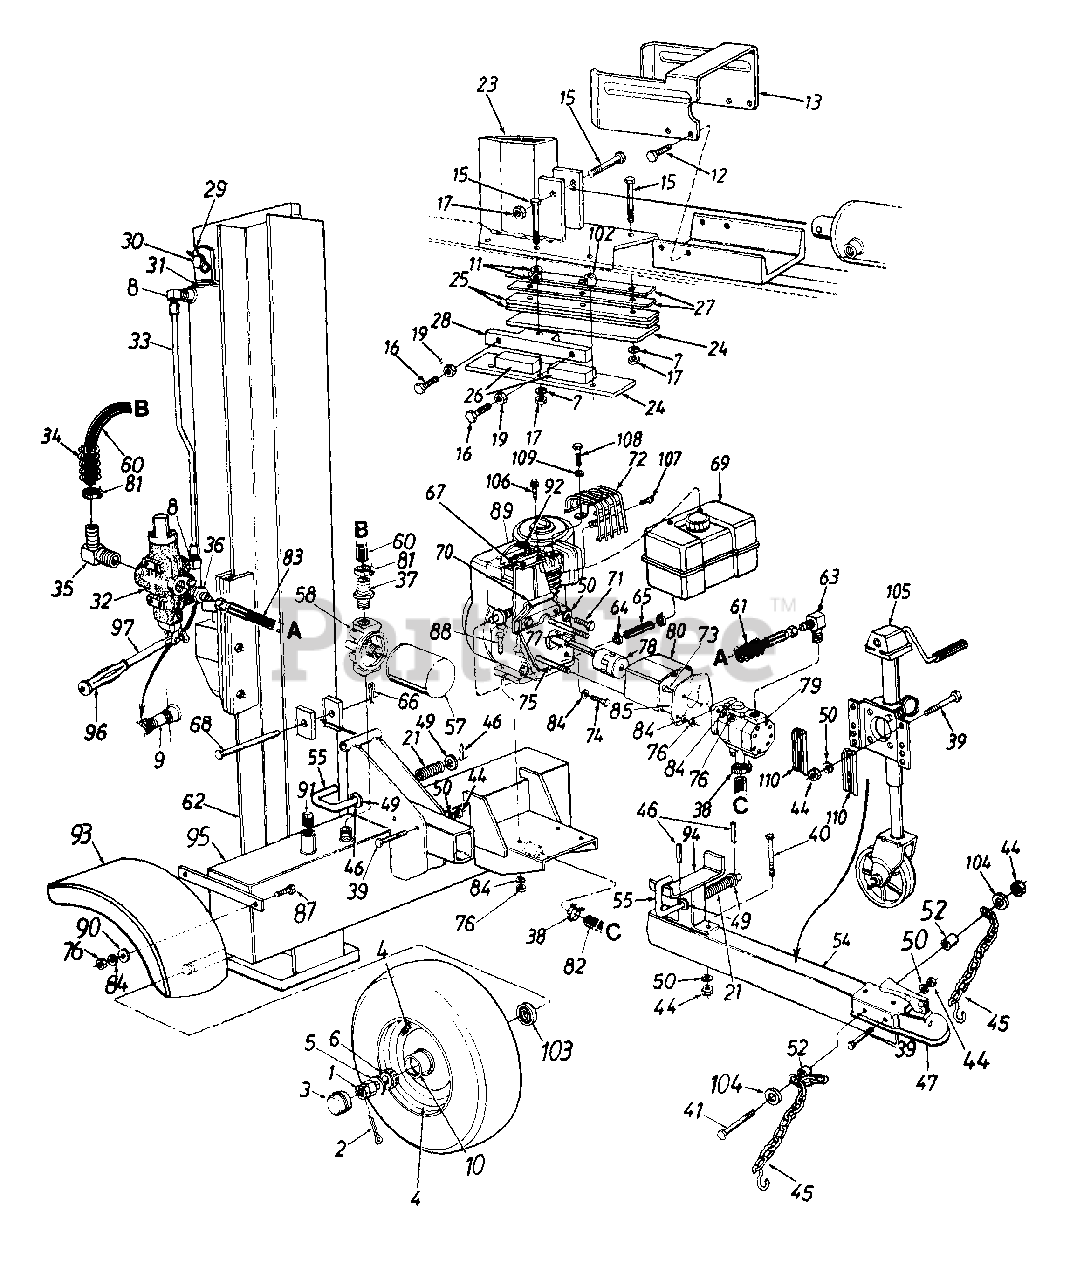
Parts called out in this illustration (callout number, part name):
1	Slotted Nut 3/4-16 Thd.
2	Cotter Pin 5/32" Dia.
3	Hub Cap
5	Fl-Wash..76" I.D. x 1.5" O.D.
6	Bearing Cone
7	L-Wash. 1/2" I.D.
8	90° Solid Male Adaptor
9	Pipe Nipple 1/2 NPT
10	Bearing Cup
11	Fl-Wash..531" 1.0. x .94" O.D.
12	Hex Cap Scr. 3/8-16 x 1" Lg.
15	Hex Bolt 1/2-20 x 2.75" Lg. (Grade 8)
16	Hex Bolt 3/8-24 x 1.5" Lg.
17	Hex L-Nut 1/2-20 Thd.
19	Hex Jam Nut 3/8-24 Thd. (Grade 5)
21	Comp. Spring 4" Lg.
29	External Cotter Pin
30	Cylinder Mounting Pin
33	Metal Pressure Tube
34	Hose Guard
35	Return Elbow
36	Adapter
37	3/4" Hose Barb.
38	Hose Clamp 1.5" O.D.
39	Hex Bolt 3/8-16 x 3" Lg. (Grade 8)
40	Hex Bolt 3/8-16 x 4.75" Lg.
41	Hex Bolt 3/8-16 x 4.25" Lg.
44	Hex Nut 3/8-16 Thd.
45	Chain - Tow Hitch
46	Roll Pin
47	Hitch Coupler
49	Fl-Wash..635" I.D. x .93" O.D.
50	L-Wash. 3/8" I.D.
52	Spacer .445" Lg.
57	Filter Element
58	Filter Head
60	Return Hose 3/4" I.D. x 44" Lg.
61	Hose Guard
64	Hose Clamp .37" Dia.
65	Fuel Line (6" Lg.)
66	Cotter Pin 1/8" Dia.
67	Tank Mtg. Brkt.
68	Hinge Pin 1/2 x 4.8" Lg.
69	Fuel Tank Ass'y.
70	Support Brkt.
71	Hex Bolt 3/8-16 x 1" Lg.
72	Muffler Guard
73	Hex Bolt 5/16-24 x 1" Lg.
74	Hex Bolt 5/16-24 x .62" Lg.
75	Hex Bolt 5/16-24 x 5.25" Lg.
76	Hex Nut 5/16-24 Thd.
77	Sq.-Key 1/4" x 2" Lg.
78	Flexible Coupling
79	Gear Pump
80	Coupling Shield
81	Hose Clamp 5/8"
82	Suction Hose 1" I.D.
83	High Pressure Hydraulic Hose 48"
84	L-Wash. 5/16" I.D.
87	Hex Bolt 5/16-24 x .75" Lg.
88	Hex Bolt 5/16-24 x 1.75" Lg.
89	Engine
90	F1-Wash..344" I.D. x .875" O.D.
91	L-Vent Pipe Plug
92	Spark Plug Boot
97	Control Handle
102	Spacer 1/2" I.D. x .86" Lg.
103	Bearing Seal Only
104	Fl-Wash. 3/8" I.D. x.87" O.D.
105	Jack Stand
106	Hex AB-Tap Scr. 1/4 x 3/4" Lg.
107	Hex Wash. Hd. Scr. #8 x .5" Lg.
108	Hex Bolt 1/4-20 x .5" Lg.
109	Fl-Wash..25" I.D. x.5" O.D.
